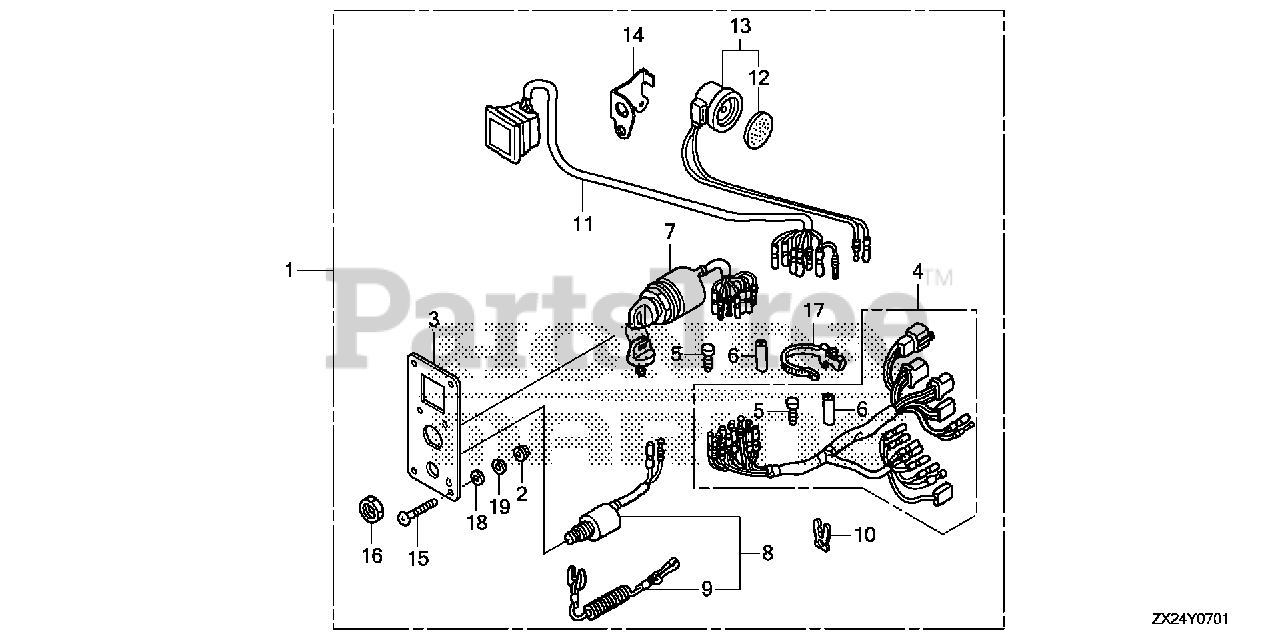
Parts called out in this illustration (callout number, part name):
1	PANEL KIT, SWITCH (4-LED)
2	NUT, FLANGE (5MM)
3	PANEL, CONTROL
4	HARNESS ASSY., SWITCH PANEL
5	PLUG, CONNECTOR (INNER)
6	PLUG, CONNECTOR (OUTER)
7	SWITCH ASSY., COMBINATION
8	SWITCH ASSY., EMERGENCY STOP
9	WIRE, EMERGENCY
10	CLIP, EMERGENCY LOCK
11	LAMP ASSY., INDICATION (4-LED)
12	PLATE, TURN SIGNAL BUZZER
13	BUZZER, WARNING
14	BRACKET, BUZZER
15	SCREW, PAN (5X40)
16	NUT, HEX. (16MM)
17	BAND, WIRE HARNESS (150MM) (NATURAL)
18	WASHER, PLAIN (5MM)
19	WASHER, SPRING (5MM)
